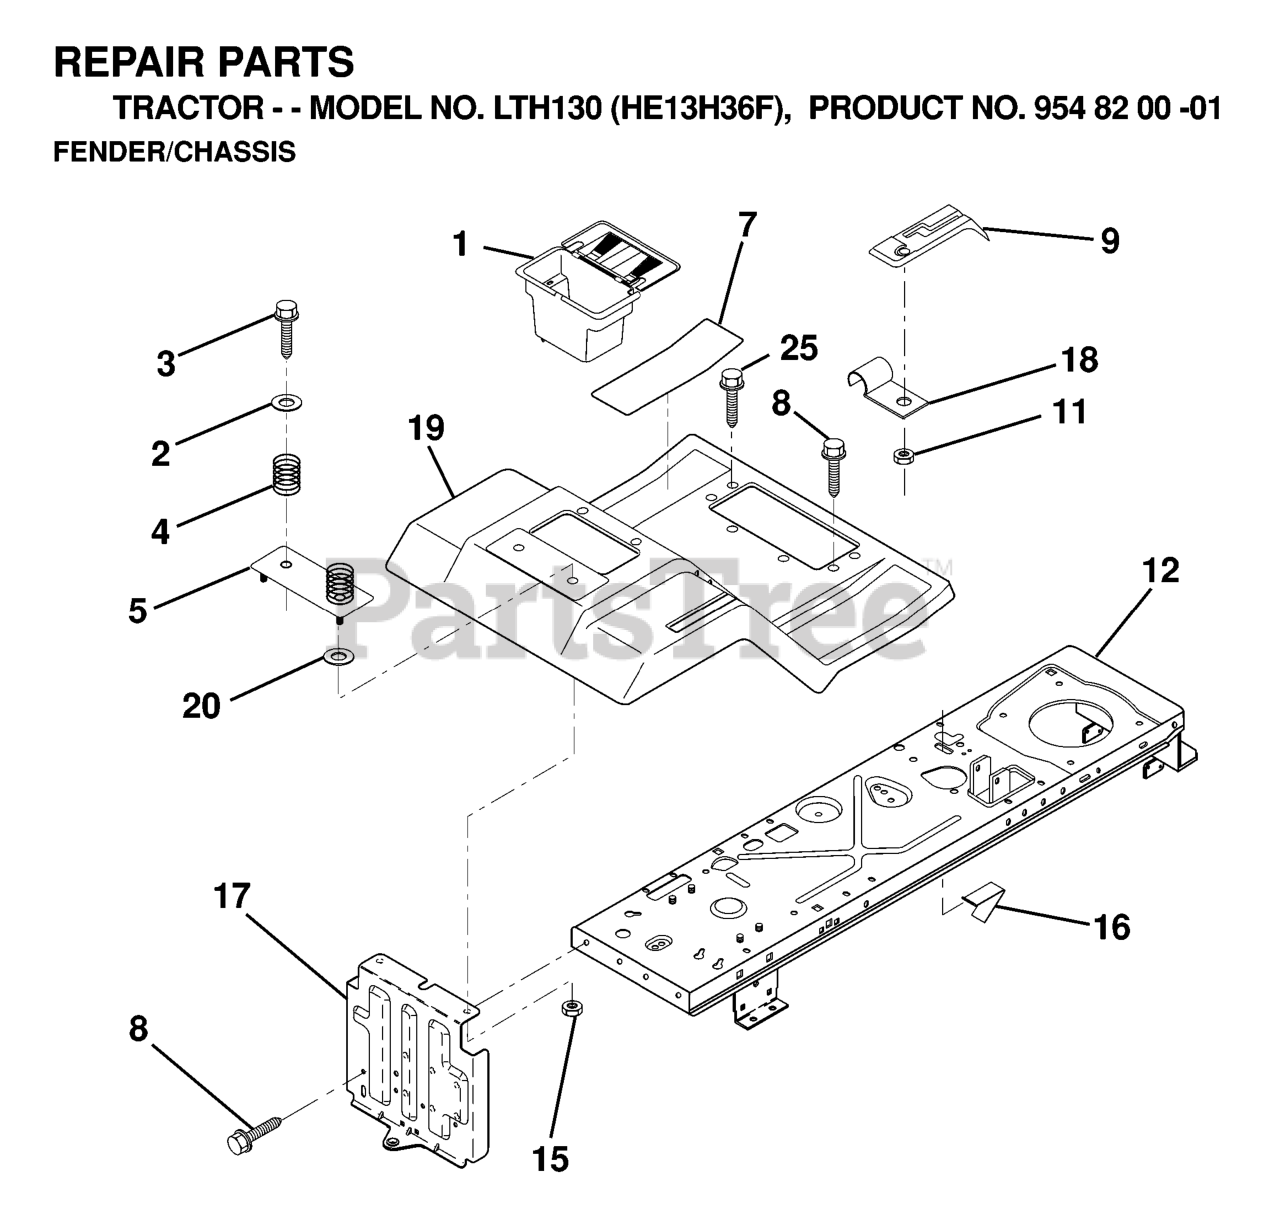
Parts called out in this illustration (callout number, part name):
1	CASE BATTERY MECH HINGE
2	WASHER
3	SCREW
4	SPRING COMPRESSION
5	PLATE ASM BATTERY
7	FOOTREST PAD
8	SCREW.THDROL.5/16-18X3/4.TTY
11	NUT.PUSH.3/16
15	Nut, Keps Blk Hex 1/4-20 UNC
16	SWITCH ACTUATOR
18	CLIP,INSULATOR
19	FENDER/FOOTREST
20	WASHER
25	Screw Hex Wsh Thdroll 5/16-18 x 1
